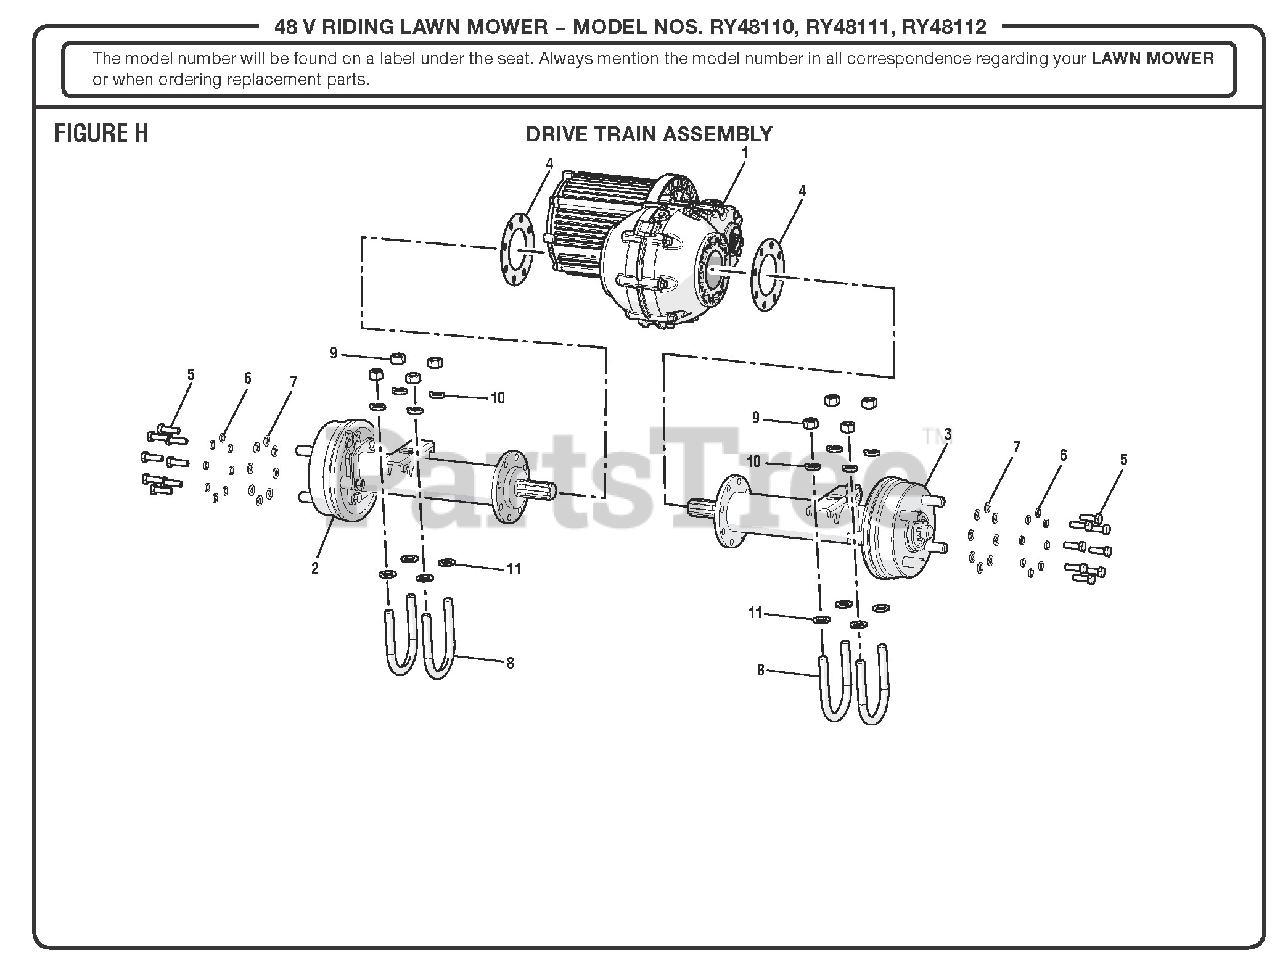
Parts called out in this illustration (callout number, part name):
1	Transaxle
2	Left Rear Axle
3	Right Rear Axle
4	Transmission Gasket
5	Bolt (M8 x 25 mm)
6	Lock Washer (8 mm)
7	Washer (OD16 x ID8.4 x 1.6t)
9	Hex Nut (M12 x 1.75 mm)
10	Spring Washer (OD20 x ID12.4 x 2t)
11	Washer (OD24 x ID13 x 2.5t)
